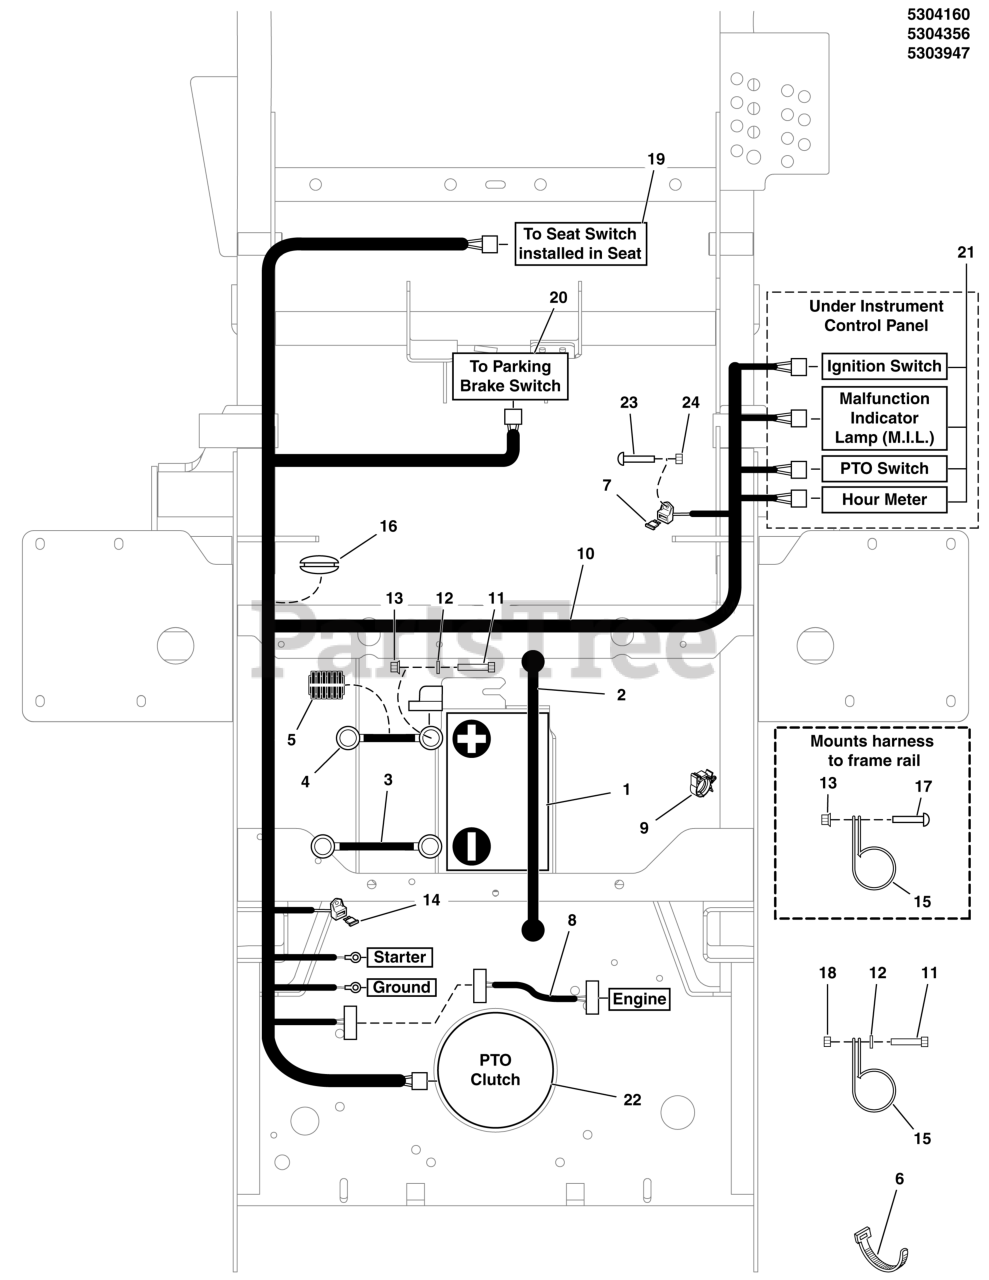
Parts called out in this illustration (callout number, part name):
1	BATTERY, WET ( BCIU1, 340 CCA)
2	STRAP, Rubber, 13"
4	BATTERY CABLE, POS, 22, 1/4-5/16
5	WIRE LOOM, 3/8 ID X 16 IN
6	TIE, SELF-LOCKING, 12"
7	FUSE, ATO, 25 AMP
8	HARNESS, Wiring
9	ROSEBUD LOOM CLIP
10	HARNESS, LARGE WIRING
11	CAPSCREW, Hex Head, 1/4-20 x 3/4 (stiffener to top of cover)
12	WASHER, Flat, 1/4
13	NUT, Serrated, Flange, 1/4-20, GR5
14	FUSE, ATO, 15 AMP (SV)
15	CLAMP, VINYL INSULATED, 1.00
16	GROMMET, 1-1/2" ID FOR 1/4" METAL
18	NUT, Flange Nylock , 1/4-20
19	Refer to: Seat Mount & Floor Group
20	Refer to: Parking Brake Group
21	Refer to: Instrument Control Panel Group
22	Refer to: Engine & PTO Group
23	SCREW- #10-24 X 1/2 ROUND PHILLIPS
24	NUT, #10-24 HEX NYLON LOCK
